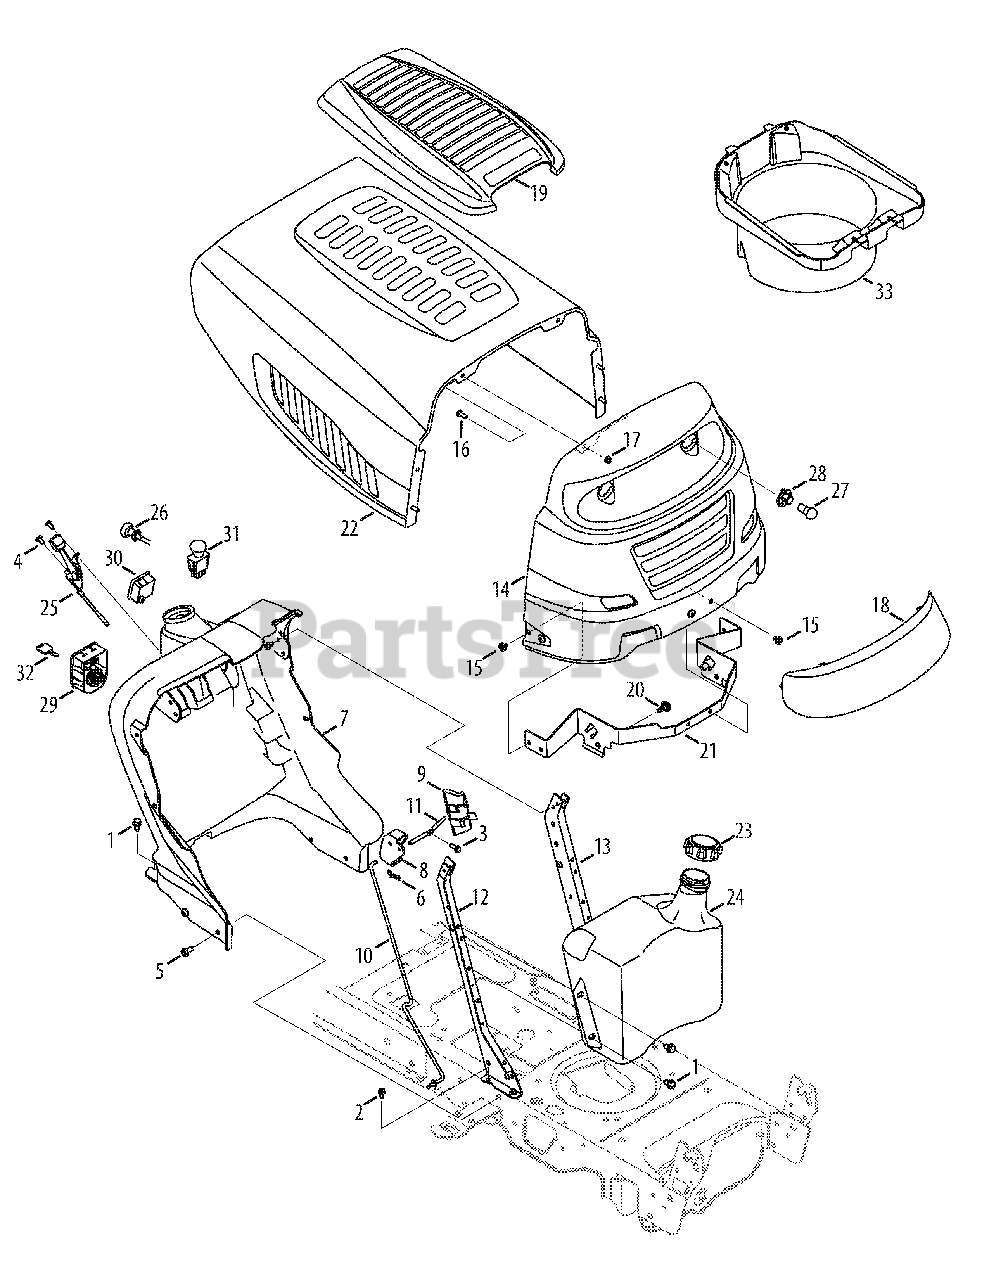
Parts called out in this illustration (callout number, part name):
1	Taptite Screw ,5/16-18:.750
2	Taptite Screw ,1/4-20:0.500
3	Hi-Lo Screw, 1/4-15:0.750
4	Screw, 1/4-14:0.625
5	Taptite Screw ,5/16-18:0.750
6	Bow Tie Cotter Pin
7	Dash Panel
8	Dash Lever
9	Cruise Cover
10	Control Rod
11	Lever
12	RH Support Plate
13	LH Support Plate
14	Grill
15	Taptite Screw ,5/16-18:0.375
16	Hex Screw, 1/4-20:.620
17	Flangelock Nut, 1/4-20
18	Grill Lens
19	Hood Scoop
20	Shoulder Screw, .43X.29:5/16-18
21	Hood Pivot Bracket
23	Fuel Cap
24	Fuel Tank
25	Throttle Cable
26	Choke Cable
28	Lamp Socket
29	Key Switch
30	Hour Meter
31	Electric PTO Switch
